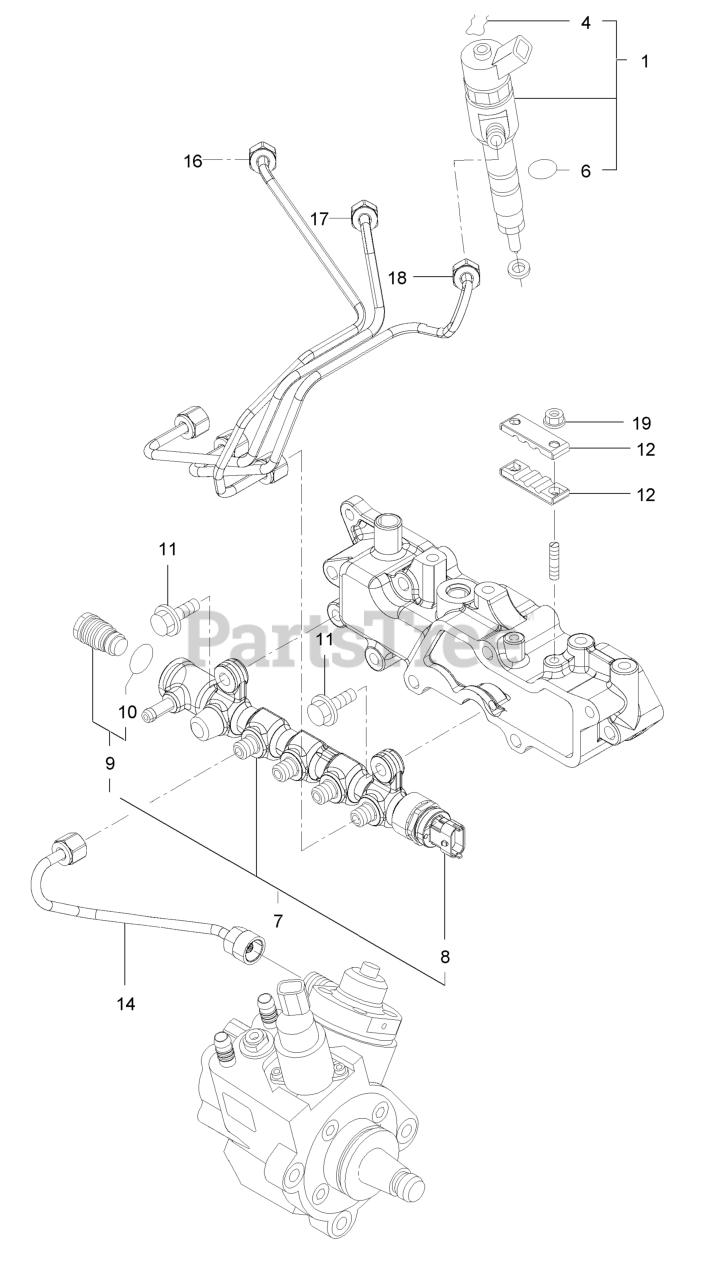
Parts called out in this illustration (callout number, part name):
1	Injector ASM
4	Ring-Retaining
7	Rail ASM
8	Sensor-Pressure, Rail
9	Valve ASM
12	Retainer
14	Rail In Pipe ASM
16	Injection Pipe ASM
17	Injection Pipe ASM
18	Injection Pipe ASM
